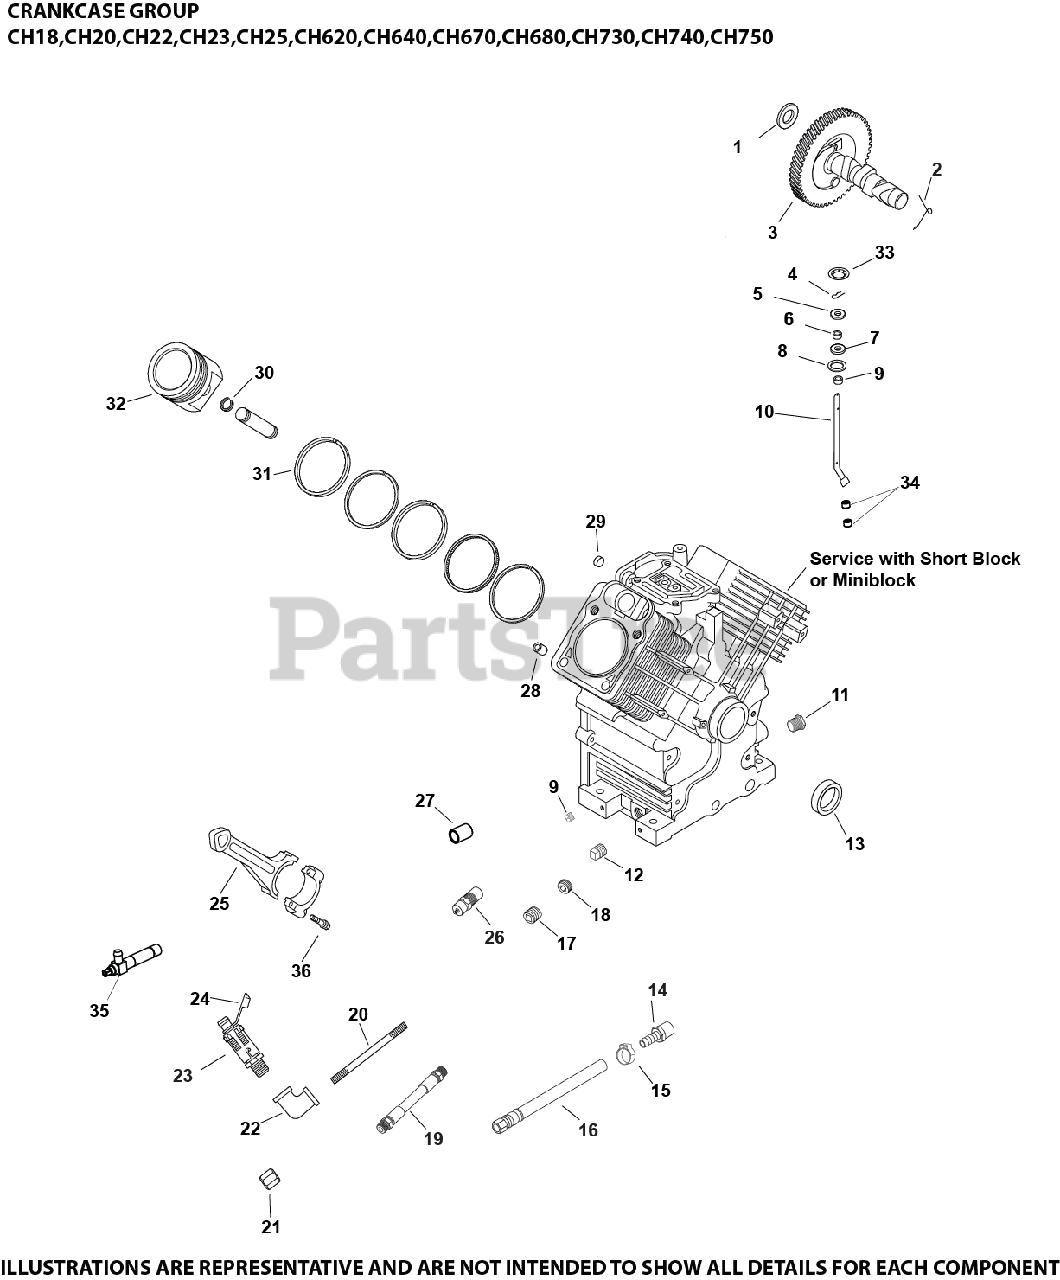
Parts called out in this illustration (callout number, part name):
3	KIT, CAMSHAFT
11	PLUG, HD PIPE 3/8"
13	SEAL, OIL (HELIX LIP)
23	KIT, OIL DRAIN VALVE
24	CAP, OIL DRAIN VALVE
25	KIT, CONNECTING ROD ASSEMBLY USE 25 067 04-S
28	PIN, LOCATING
29	PLUG, CUP
30	RETAINER, PISTON PIN
31	RING SET(STD)STYLE B-1.2mm Tp RING THICK
31	RING SET(.08)STYLE B-1.2mm Tp RING THICK
31	RING SET(.25)STYLE B-1.2mm Tp RING THICK
31	RING SET(.50)STYLE B-1.2mm Tp RING THICK
32	PISTON W/RINGS (STYLE B)(STD) - RING SET 25 108 01-S
32	PISTON W/RINGS (STYLE B)( 0.08) - RING SET 25 108 02-S
32	PISTON W/RINGS (STYLE B)(0.25) - RING SET 25 108 03-S
32	PISTON W/RINGS (STYLE B)(0.50) - RING SET 25 108 04-S
36	KIT, ROD BOLTS
